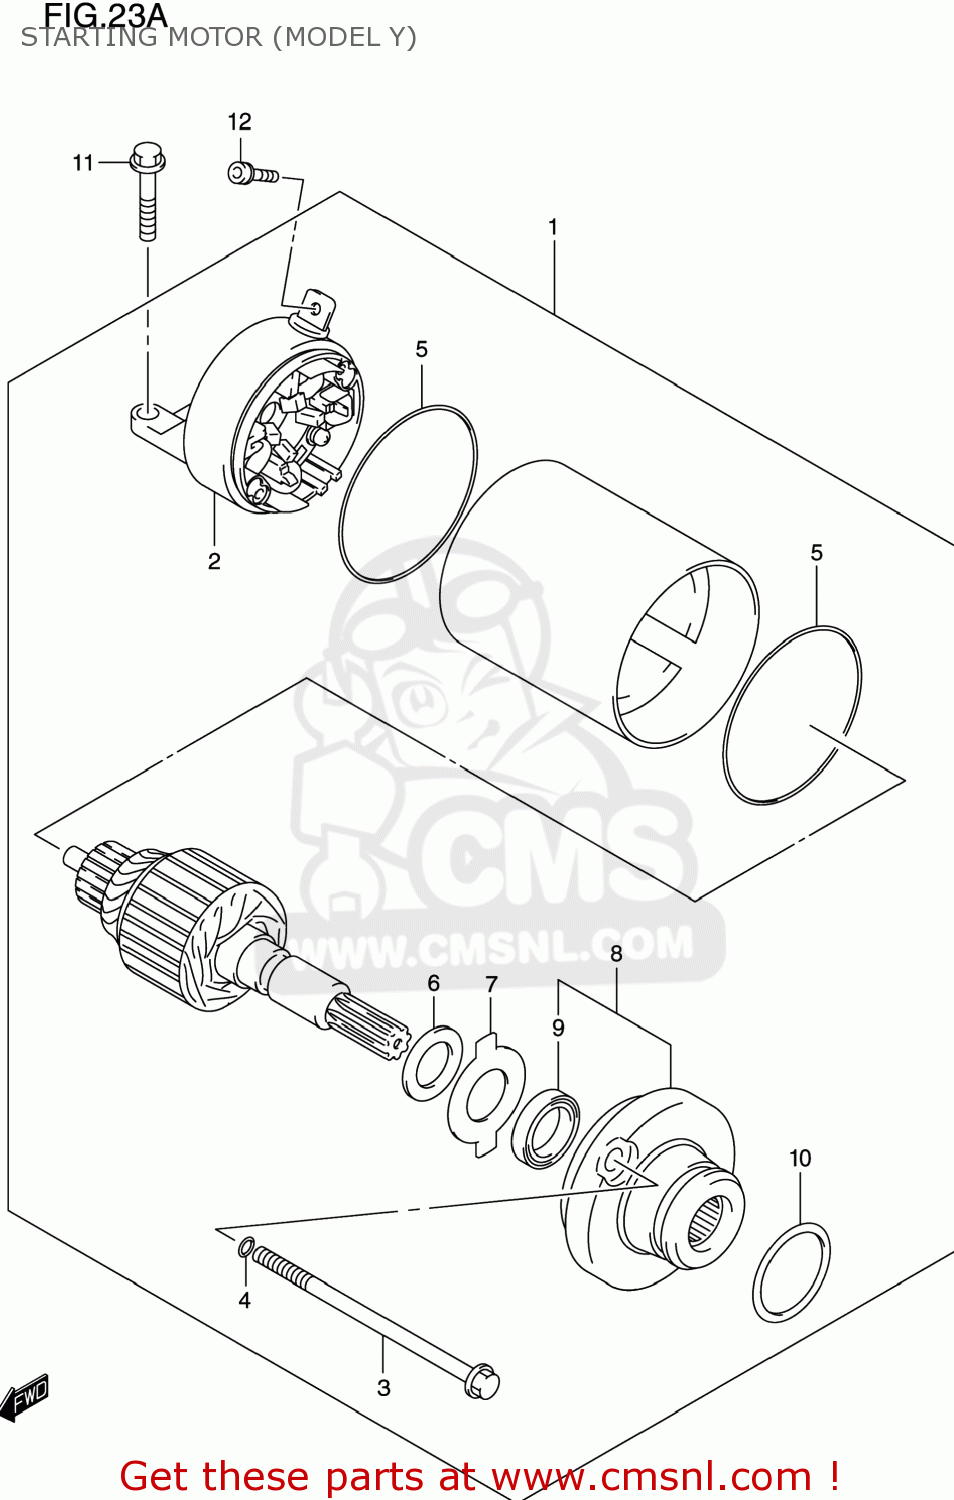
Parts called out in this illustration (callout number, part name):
1	MOTOR ASSY,STARTING
2	FRAME ASSY,COMMUTATOR END
3	BOLT
4	O RING
5	O RING
6	SHIM
7	PLATE,LOCK
8	BRACKET
9	SEAL,OIL
10	O RING(D:3,ID:24.5)
11	BOLT(6X20)
12	SCREW(5X8)
